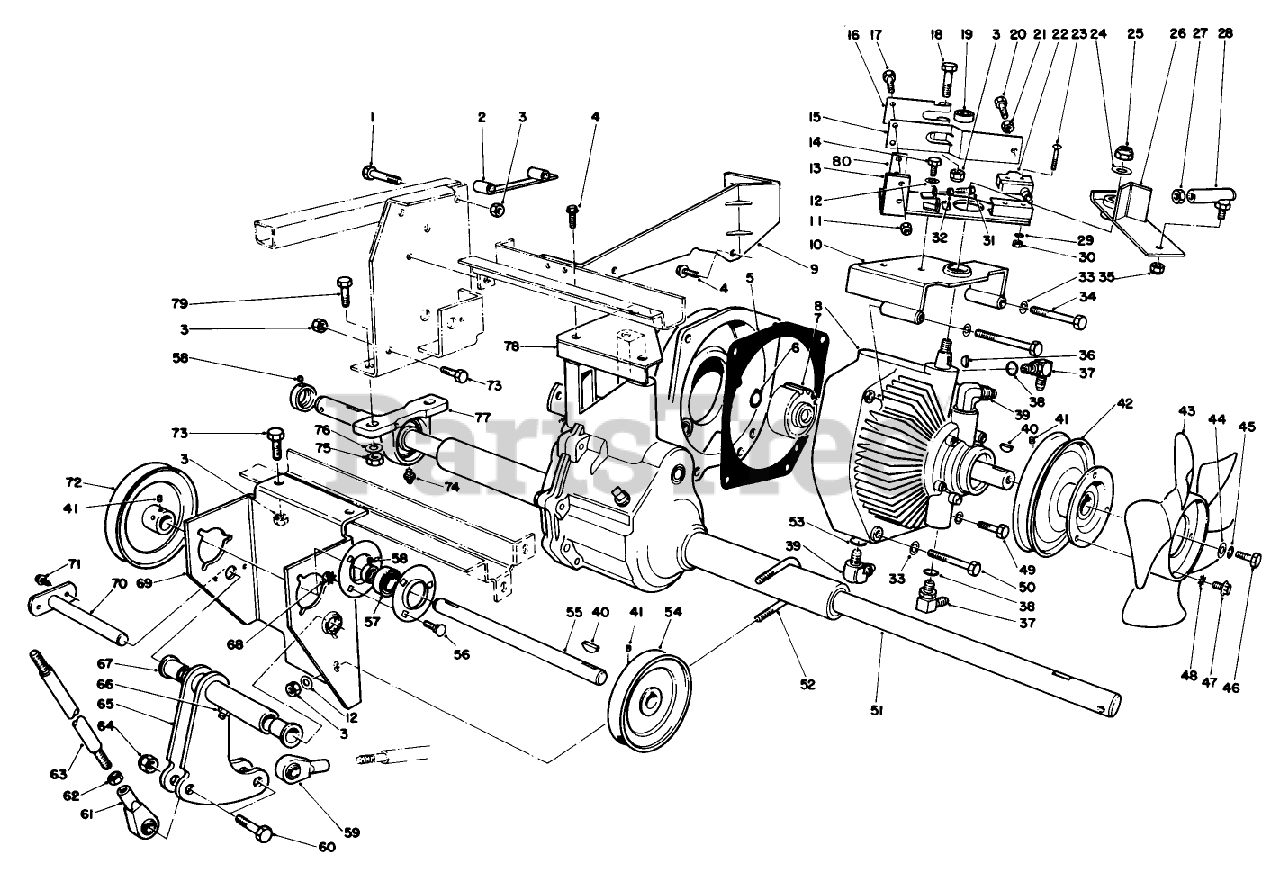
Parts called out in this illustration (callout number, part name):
1	SCREW-HH
2	Spacer
3	NUT-LOCK, NI
4	SCREW-HHF
5	TRANS GASKET
6	RING-SNAP, EXTERNAL
7	GEAR-SPUR
8	HYDROSTATIC TRANS.
9	Bracket-Transaxle
10	TR CONT BRKT WA B
11	NUT-LOCK, NI
12	WASHER-PLAIN
13	Traction Plate
14	SCREW-HH
15	EXTENDED LEAF SPRING ASM
16	SPRING-LEAF
17	SCREW-HH
18	SCREW-HH
19	BEARING-BALL
20	SCREW-HH
21	NUT-JAM
22	Switch
23	SCREW-MACHINE
24	WASHER-FLAT
25	NUT-LOCK, NI
26	Traction Lever
27	NUT-JAM
28	JOINT-BALL
29	WASHER-LOCK, INTERNAL
30	NUT-HEX
31	SCREW-HH
32	NUT-JAM
33	WASHER-LOCK
34	SCREW-HH
35	NUT-LOCK
36	KEY-WOODRUFF
37	FITTING-HYD, 90 DEG
38	O-RING
39	FITTING-ELBOW, 90 DEG
40	KEY-WOODRUFF
41	SCREW-SET, SQH
42	TRANS PULLEY
43	FAN 8"
44	WASHER-FLAT
45	WASHER-LOCK
46	SCREW-HH
47	Screw
48	WASHER-LOCK/EXT
49	SCREW-HH
50	SCREW-HH
51	Gear Reduction & Differential Assembly
52	U-BOLT
53	O-RING
54	JACKSHAFT INPUT PULLEY
55	JACKSHAFT
56	BOLT-CARR
57	Bearing w/Collar & Flange
58	SCREW-SET, HSH
59	BALL JOINT LH
60	SCREW-HH
61	BALL JOINT RH
62	NUT-JAM
63	Rod-Steering
64	NUT-HEX
65	Bellcrank (Incl. Ref. #66 & 67)
66	GREASE FITTING
67	BUSHING PM
68	NUT-KEPS
69	Bracket-Jackshaft
70	Shaft-Bellcrank
71	SCREW-HHFTF
72	JACKSHAFT OUTPUT PULLEY
73	SCREW-HH
74	FITTING-GREASE
75	NUT-LOCK, NI
76	WASHER-FLAT
77	Bearing-Pillow Block w/Collar
78	TRANSAXLE PLATE
79	SCREW-HH
80	SHIM-ARM, SPRING
